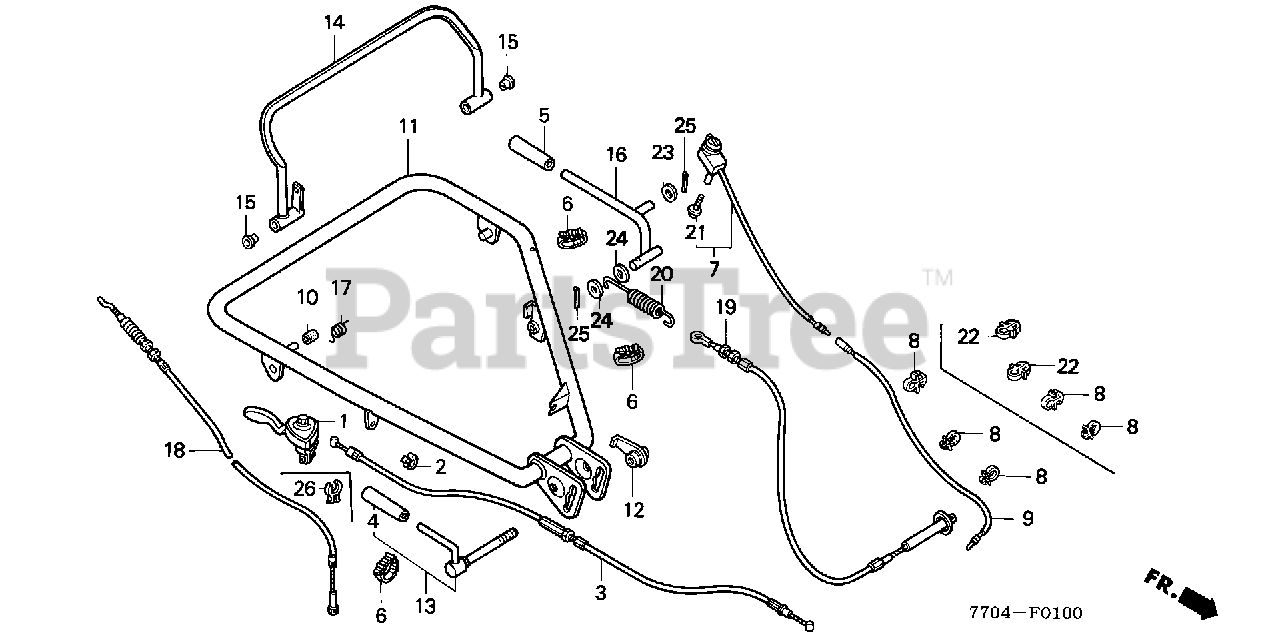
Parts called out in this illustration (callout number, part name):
1	LEVER ASSY., THROTTLE (STEEL PRESSED LEVER)
1	LEVER ASSY., THROTTLE (RESIN MOLDED LEVER)
2	M-CLIP (STEEL PLATE CLIP)
3	CABLE, THROTTLE (NOT AVAILABLE)
3	CABLE, THROTTLE
4	GRIP, FR. CLUTCH LEVER
5	GRIP, CLUTCH LEVER
6	BAND B1, WIRE
6	BAND, CABLE (120MM) (BLACK)
7	SWITCH ASSY., ENGINE STOP
8	HOLDER, STOP SWITCH WIRE
9	WIRE, ENGINE STOP
10	RUBBER, SHOE SPRING
11	PIPE, HANDLE (CHROME PLATED) (NOT AVAILABLE)
12	NUT, HANDLE LOCK
13	LEVER, HANDLE ADJUSTING
14	LEVER, CLUTCH *NH105* (MAT BLACK)
15	BUSH, CLUTCH LEVER
16	LEVER, MAIN CLUTCH
17	SPRING, MAIN CLUTCH ARM RETURN
18	CABLE, MAIN CLUTCH
19	CABLE, ROTARY CLUTCH
20	SPRING, ROTARY CLUTCH
21	BOLT (3X12) (SEMS)
23	WASHER, PLAIN (10MM)
24	WASHER, PLAIN (10MM)
25	PIN, SPLIT (2.0X22)
25	PIN, SPLIT (2.0X35)
26	CLIP, THROTTLE (RESIN MOLDED CLIP)
